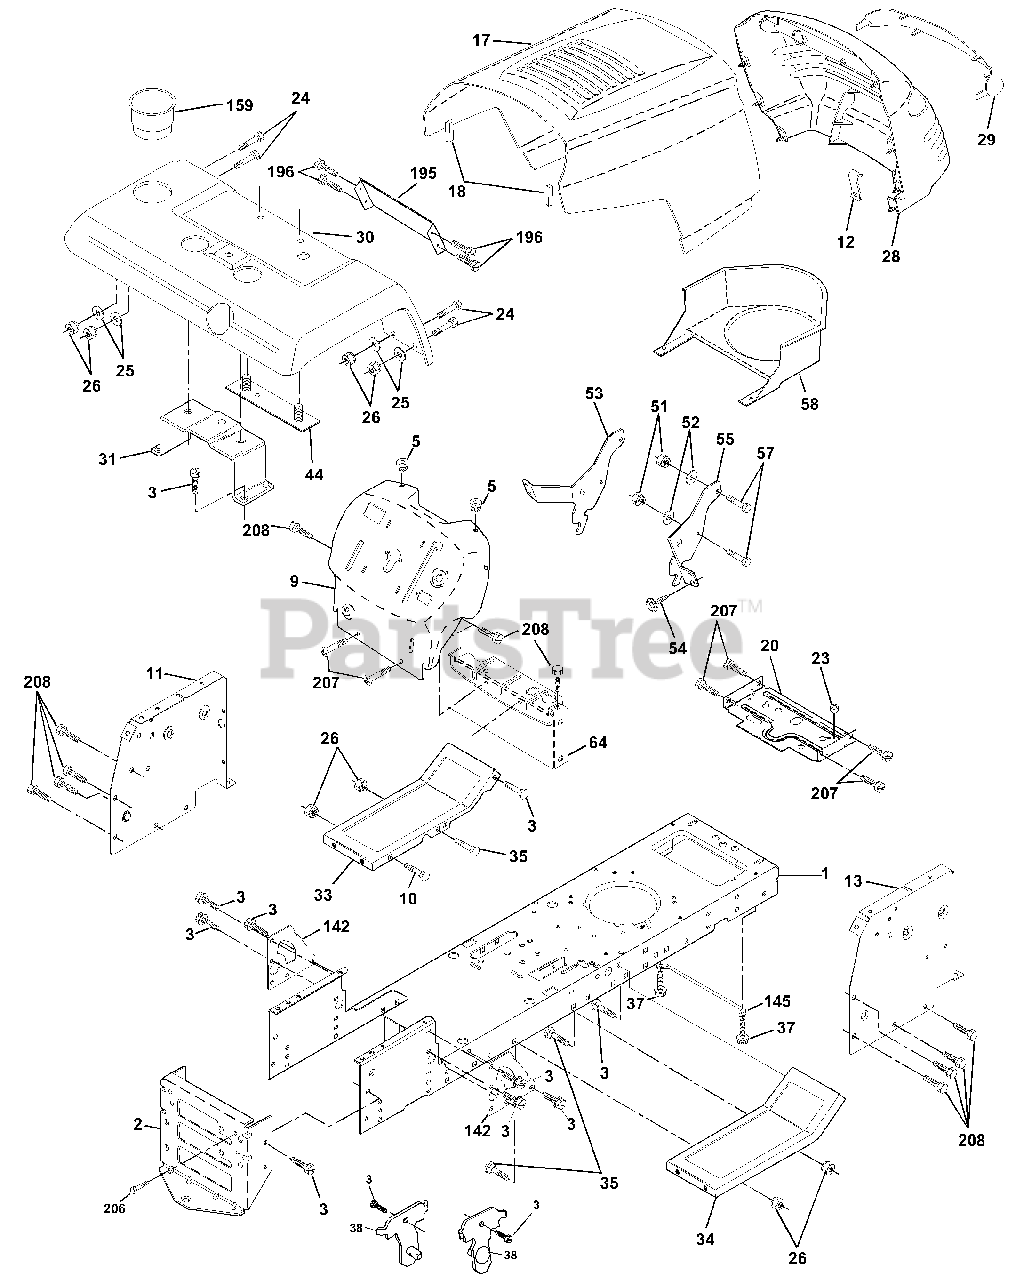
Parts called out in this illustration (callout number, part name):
1	Chassis
2	Drawbar
3	Screw 3/8-16x3/4
5	Bumper Hood/Dash
10	Bolt Carriage 3/8-16 x 1
11	Panel Dash Lh
12	Clip Tinnerman
13	Panel Dash Rh
17	Hood LT/PL
18	Bumper Hood
20	Plate Mtg Battery Fuel Tank Fr
23	Bushing
24	Bolt Fin Hex 3/8-16 x 1 Gr 5
25	Washer 13/32 X 13/16 X 12 Ga
26	Nut Lock Hex W/Ins 3/8-16 Unc
28	Grille LT/PL
29	Lens LT/PL
30	Fender Pnt YTGT w/Shift w/fuel
31	Bracket Fender
33	Footrest Pnt Lh
34	Footrest Pnt Rh
35	Bolt Rdhd Sht Sqnk 3/8-16 x 3/4
37	Screw Thdrol 6/16-18 x 1/2 TYT
38	Bracket, Asm. Pivot Mower Rear
44	Strap Asm Fender
51	Nut Lock Hex W/Ins 1/4-20
52	Washer 9/32 x 7/8 x 16 Ga.
53	Bracjet Grukke Lh
54	Screw Hex Wshd 8-18 x 7/8
55	Bracket Grille Rh
57	Bolt Hex 1/4-20 x 3/4
58	Duct Air
64	Dash Lower STLT
142	Plate Reinforcement STLT
145	Rod Pivot Chassis/Hood
159	Cupholder
195	Panel Pnt Fender YT/GT
196	Screw Tap Tite 1/4-20 x 1/2
206	Bolt Shoulder 5/16-18
207	Screw Thdrol 5/16-18 x 1/2
208	Screw Thdrol 3/8-16 x 1/2
